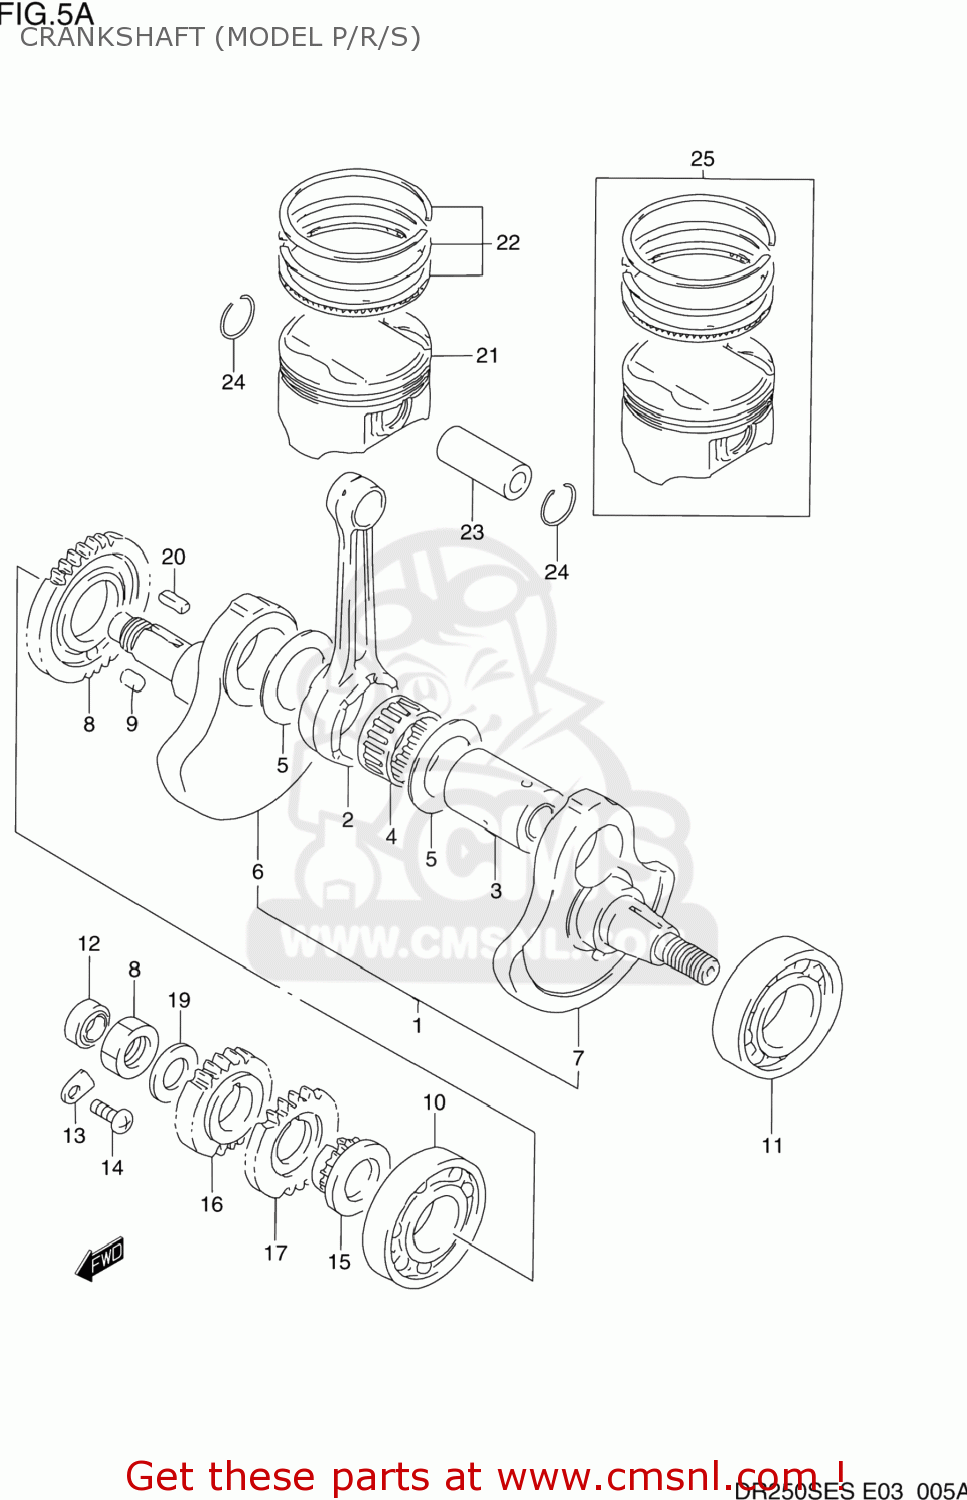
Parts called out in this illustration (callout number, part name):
1	CRANKSHAFT ASSEMBLY
2	CONNECTING ROD
3	PIN COMP,CRANK
4	BEARING(34X43X22)
5	WASHER(34X52X1)
6	CRANKSHAFT,RIGHT
7	CRANKSHAFT,LEFT
8	GEAR,CRANK BAL DRIVE(NT:37)
9	PIN
10	BEARING(30X72X19)
11	BEARING(35X72X17)
12	SEAL,OIL(14X24X6)
13	RETAINER,BEARING
14	SCREW
15	SPROCKET,CAM CHAIN DRIVE
16	GEAR,PRIMARY DRIVE (NT:
17	GEAR,OIL PUMP DRIVE (NT
18	NUT
19	WASHER
20	KEY
21	PISTON (73.00MM)
22	RING SET,PISTON
23	PIN,PISTON
24	RING,SNAP
25	PISTON SET(OS:0.5)
